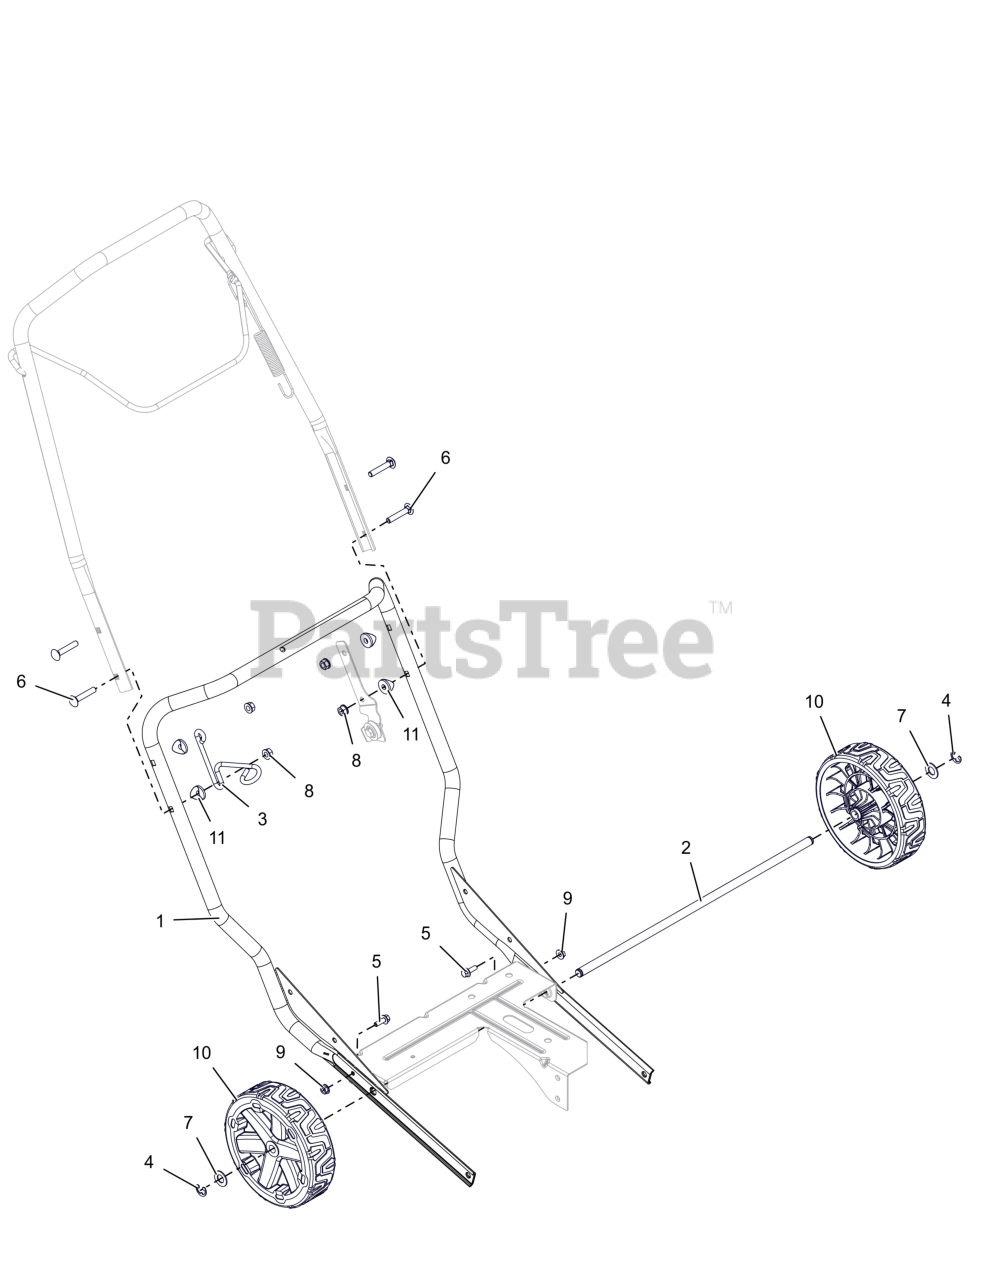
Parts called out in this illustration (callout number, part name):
1	HANDLEBAR, LOWER - W/DECAL
2	SHAFT, AXLE
3	HOLDER, RECOIL
4	RG-RTNG-EXT .500X.042 (E)
5	BLT,HEX-FLG .25-20X.75 G5 ZCC
6	BLT, RHSN .31-18X1.75 G5 ZCC
7	WSHR, FLT .531X1.00X.063 ZCC
8	NUT,LK-CTR-FLG .31-18 GF ZCC
9	NUT-LK-TOP-FLG .250-20 GF ZCC
10	TIRE/WHEEL- 7.5 X 2.0
11	SPACER, HANDLEBAR (OD .875)
